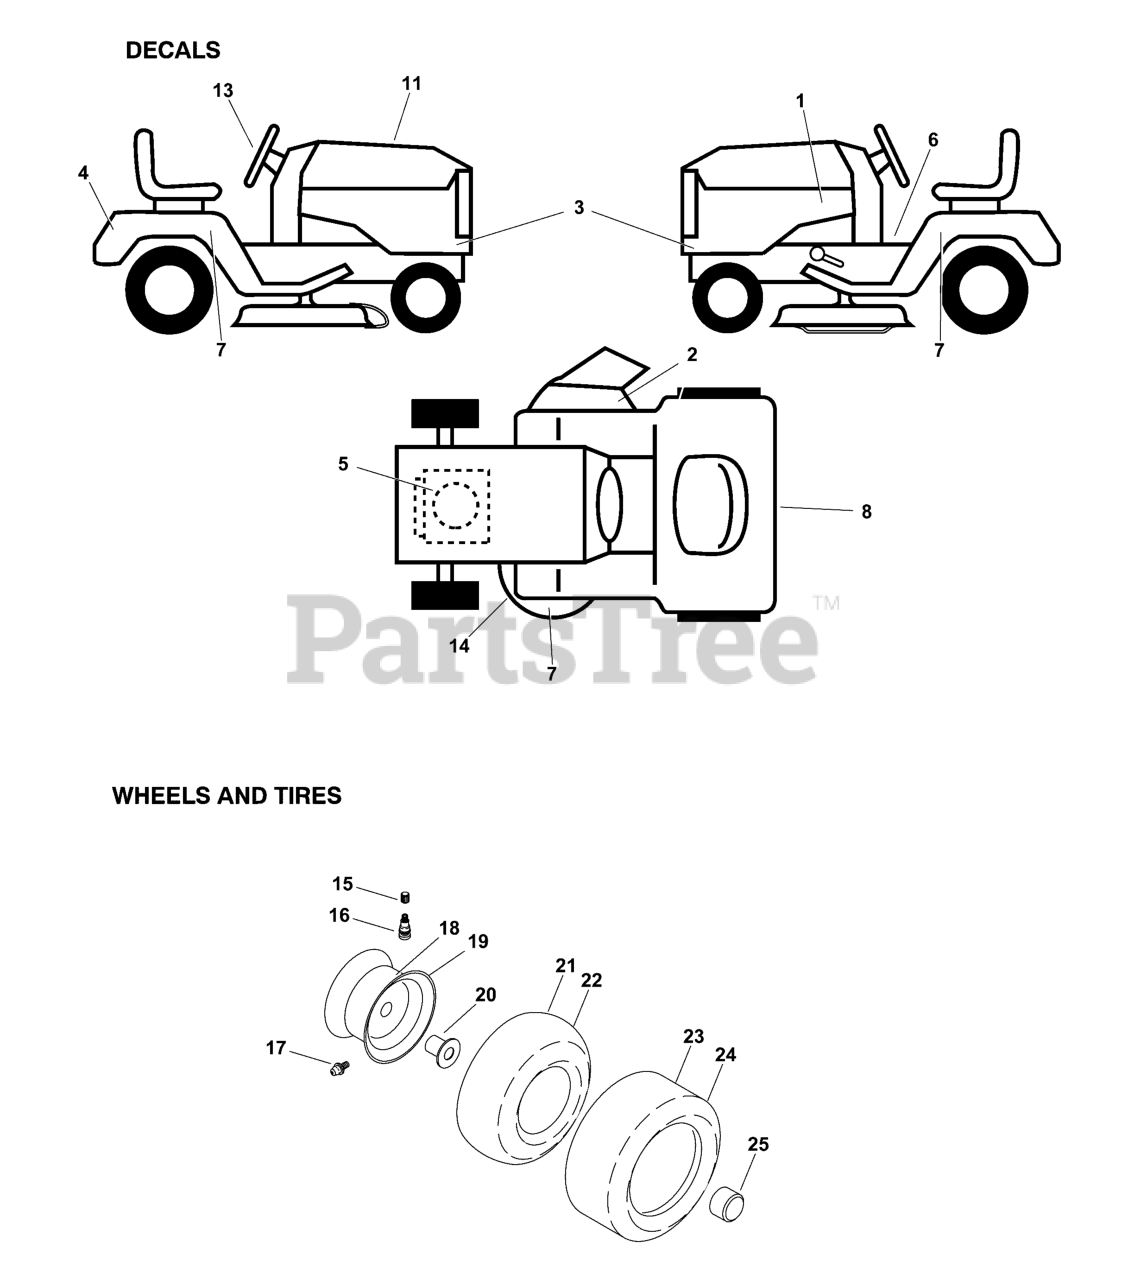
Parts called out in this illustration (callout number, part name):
1	Decal, Hood RH/LH
2	DECAL, Keep Hand Away
4	DECAL, Fender
5	DECAL, Engine H.P.
6	Decal, Fender Operator's
7	DECAL, Fender LH/RH
8	DECAL, UPD Barcode
13	Decal, Steering Wheel
14	Decal, Mower Schematic
14	Pad, Footrest RH
14	Pad, Footrest, LH
14	Decal, Guide, Quick Start
14	Decal, Bypass
15	Cap, Valve, Tire
16	Stem, Valve
17	FITTING, Grease
18	ASSEMBLY, Front Rim
19	Rim Assembly, Rear
20	BEARING, Flange
21	Tube, Front
22	Tube, Rear
23	TIRE, Front 15 x 6-6
24	Tire, Rear 20 x 8-8
25	Cap, Axle
